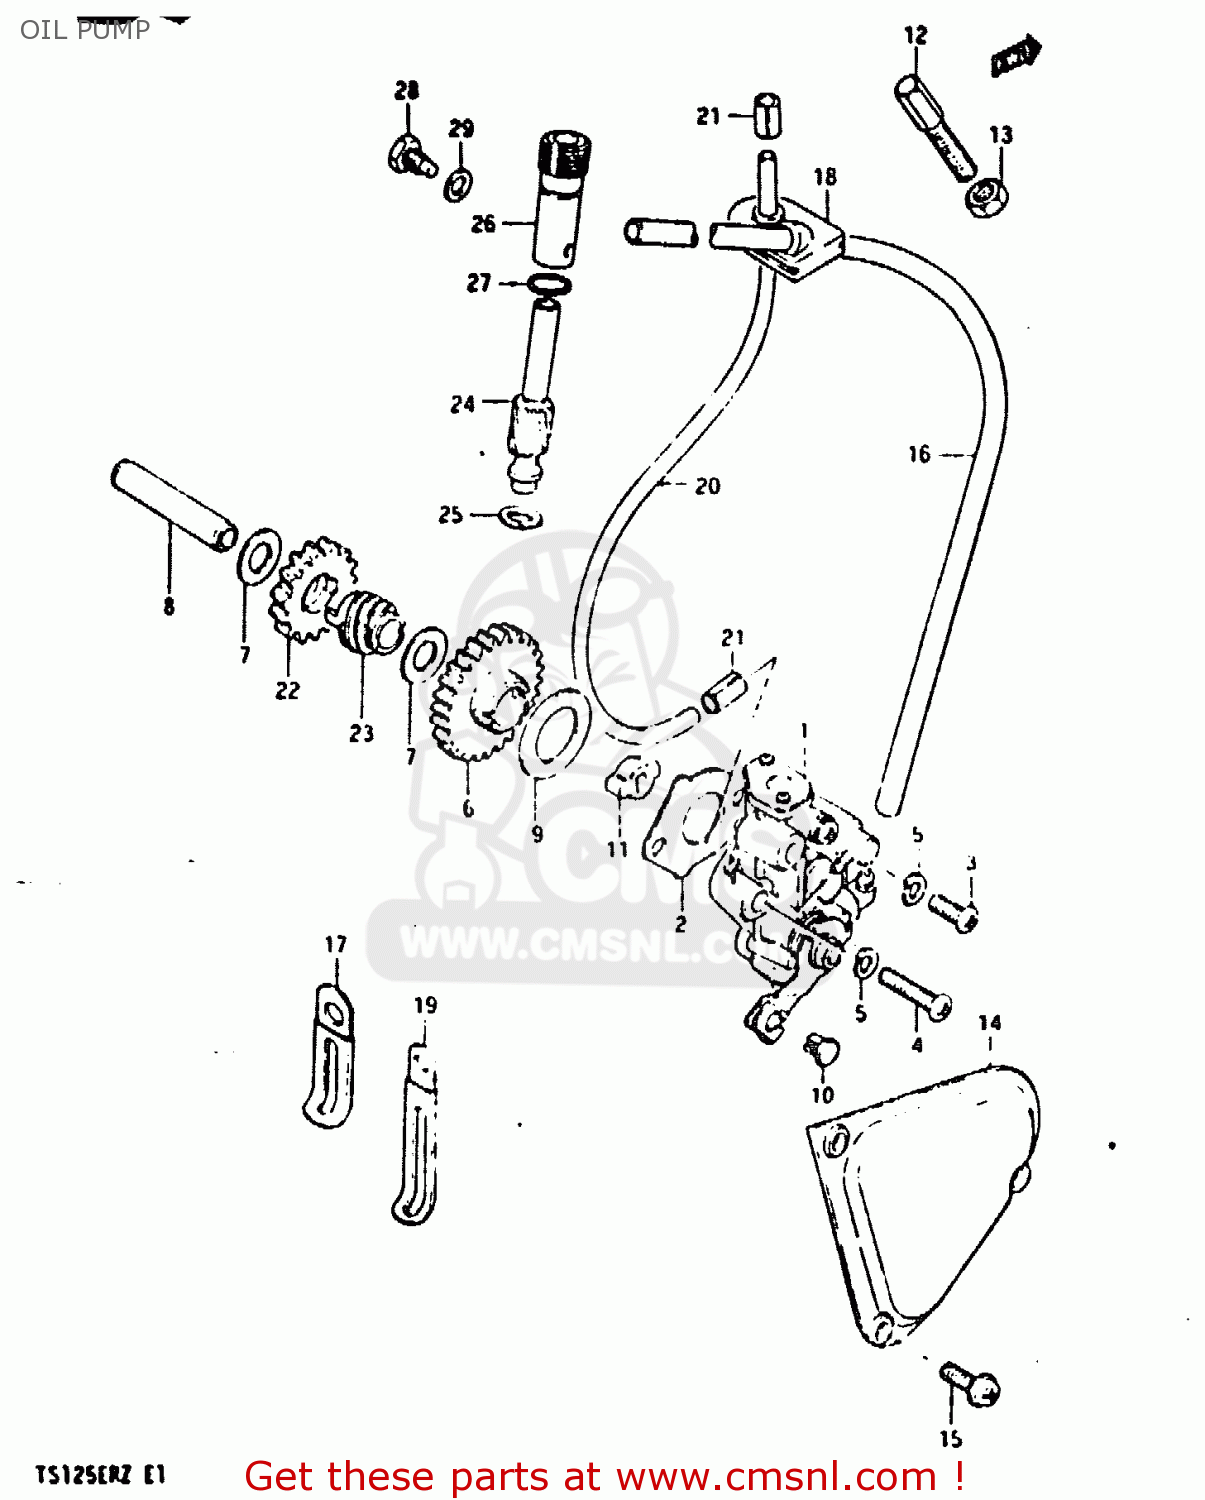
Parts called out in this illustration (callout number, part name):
1	PUMP,OIL
2	GASKET,OIL PUMP (NAS)
3	SCREW
4	SCREW
5	LOCK WASHER
6	GEAR, DRIVEN
7	WASHER(10X18X4)
8	SHAFT,DRIVEN GEAR
9	WASHER(21X32X1.5)
10	TERMINAL,CABLE
11	PIECE,OIL PUMP DRIVE
12	BOLT
13	NUT
14	COVER, OIL PUMP
15	SCREW
16	HOSE, INLET (L:550)
17	CLAMP
18	GROMMET,OIL HOSE NO.2
19	CLAMP
20	HOSE
21	CLIP
22	GEAR,TACHOMETER DRIVE NO.1
23	GEAR,TACHOMETER DRIVE NO.2
24	GEAR,TACHOMETER DRIVEN
25	WASHER(8X13.7X1)
26	SLEEVE,TACHOMETER DRIVE GEAR
27	O RING(D:1.3,ID:9.6)
28	BOLT
29	GASKET(6.2X11X1).2 (NAS)
